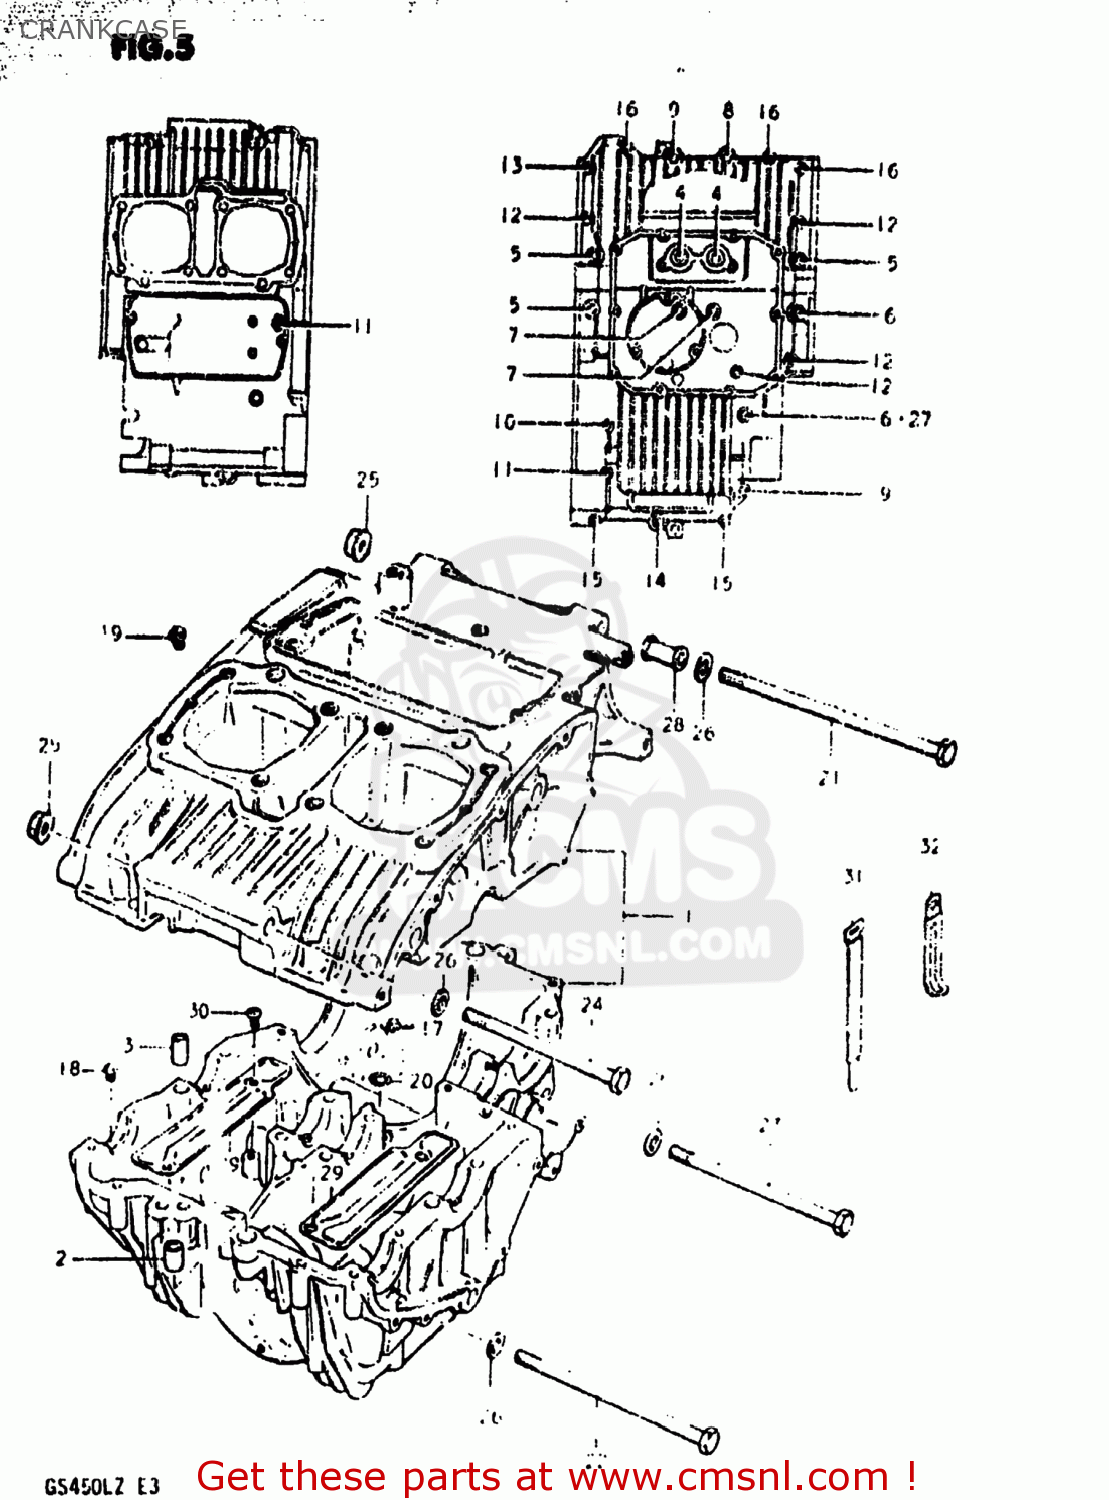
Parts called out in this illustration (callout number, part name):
1	CRANKCASE SET
2	PIN(10.4X13X22)
3	PIN (11X20)(SUS)
4	BOLT
5	BOLT
6	BOLT
7	BOLT
8	BOLT 8X65
9	BOLT (8X45)
10	BOLT
11	BOLT
12	BOLT (6X90)
13	BOLT (6X70)
14	BOLT 6X65
15	BOLT ,6X50
16	BOLT,UNDER
17	JET
18	JET
19	JET
20	O-RING
21	BOLT 10X250
22	BOLT(10X210)
23	BOLT 10X160
24	BOLT
25	NUT 10MM
26	WASHER
27	GASKET 8.2X14X1 (NAS)
28	SPACER,ENGINE MOUNT
29	PLATE,OIL SEPARATOR
30	SCREW
31	CLAMP
32	CLAMP
